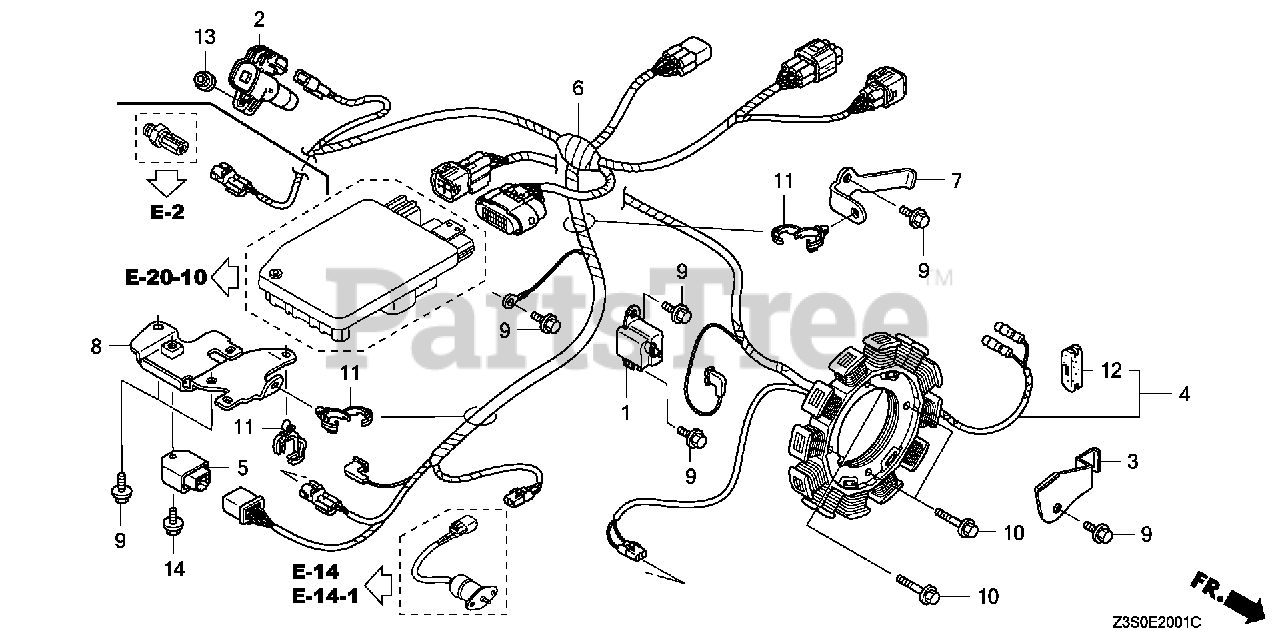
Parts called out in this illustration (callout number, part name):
1	COIL ASSY., PULSER
2	COIL, IGNITION
3	CLAMP, WIRE
4	COIL ASSY., CHARGE (20A)
5	RECTIFIER ASSY.
6	WIRE HARNESS ASSY., ENGINE
7	BRACKET, HARNESS CLIP (A)
8	BRACKET, HARNESS (C)
9	BOLT, FLANGE (6X14) (CT200)
10	BOLT, FLANGE (6X32) (CT200)
11	CLIP, HARNESS
12	GROMMET, CORD
13	NUT, FLANGE (6MM)
14	BOLT, FLANGE (6X12)
